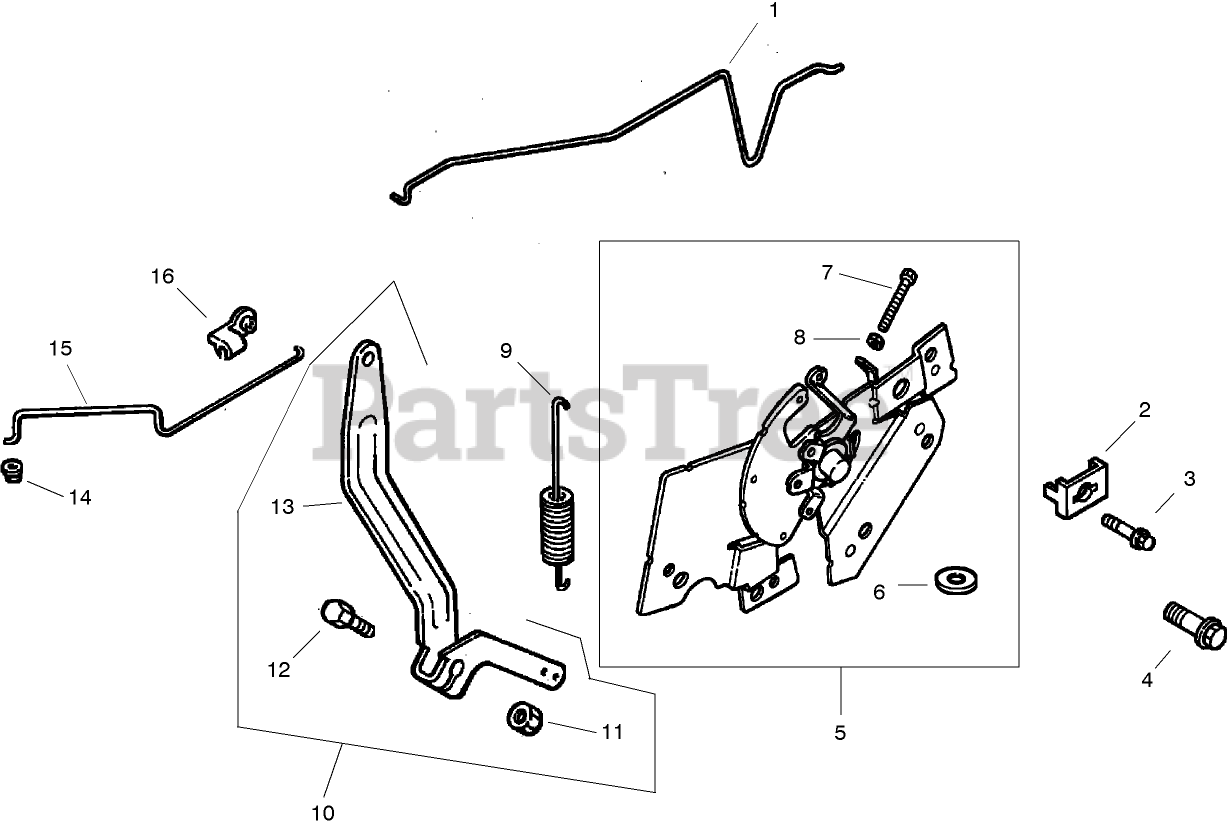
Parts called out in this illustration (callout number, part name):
1	Linkage-Choke
2	CLAMP-CABLE
3	SCREW-FLANGE, THREAD FORMING (M5X0.8X16)
4	Screw-Socket, 6 Lobed (Thread Forming, M6x1.0x20)
5	Control- Speed ASM (Incl 6,7)
6	Spacer-Shim
7	Screw (M4x0.7x30)
8	NUT (M4X0.7)
9	Spring-Governor
10	Kit, Governor Lever (Incl 10-12)
11	Nut-Flange, Hex (1/4-20)
12	Bolt-Square Neck, Round Head (1/4-20x1)
13	Lever-Governor
14	BUSHING-LINKAGE, THROTTLE
15	Linkage-Throttle
16	BUSHING-RETAINING, LINKAGE
